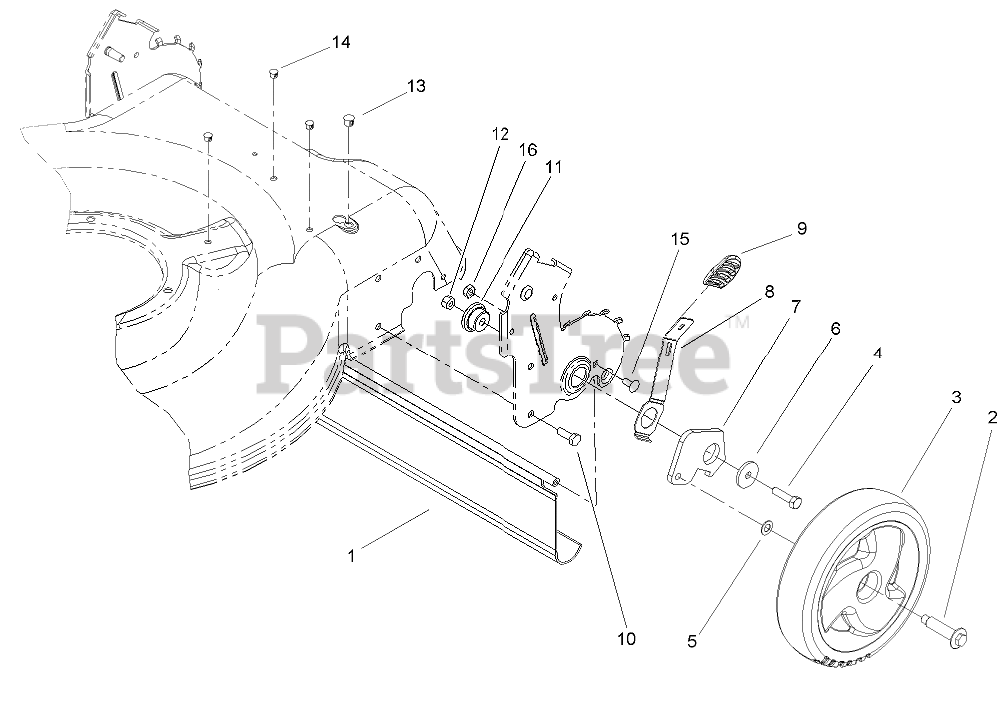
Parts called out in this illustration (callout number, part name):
1	Shield-Trailing
2	BOLT-SHOULDER
3	WHEEL ASM (59505)
4	SCREW-HH
5	WASHER
6	Washer-Flat
7	Arm-Pivot, Rear (LH)
8	Arm-Spring
9	Knob-Lever, HOC
10	SCREW-HH
11	Bushing-Mount, HOC
12	NUT-LOCK, NI
13	Plug-Dome
14	Plug-Dome
15	SCREW-CARR
16	NUT-LOCK, NI
